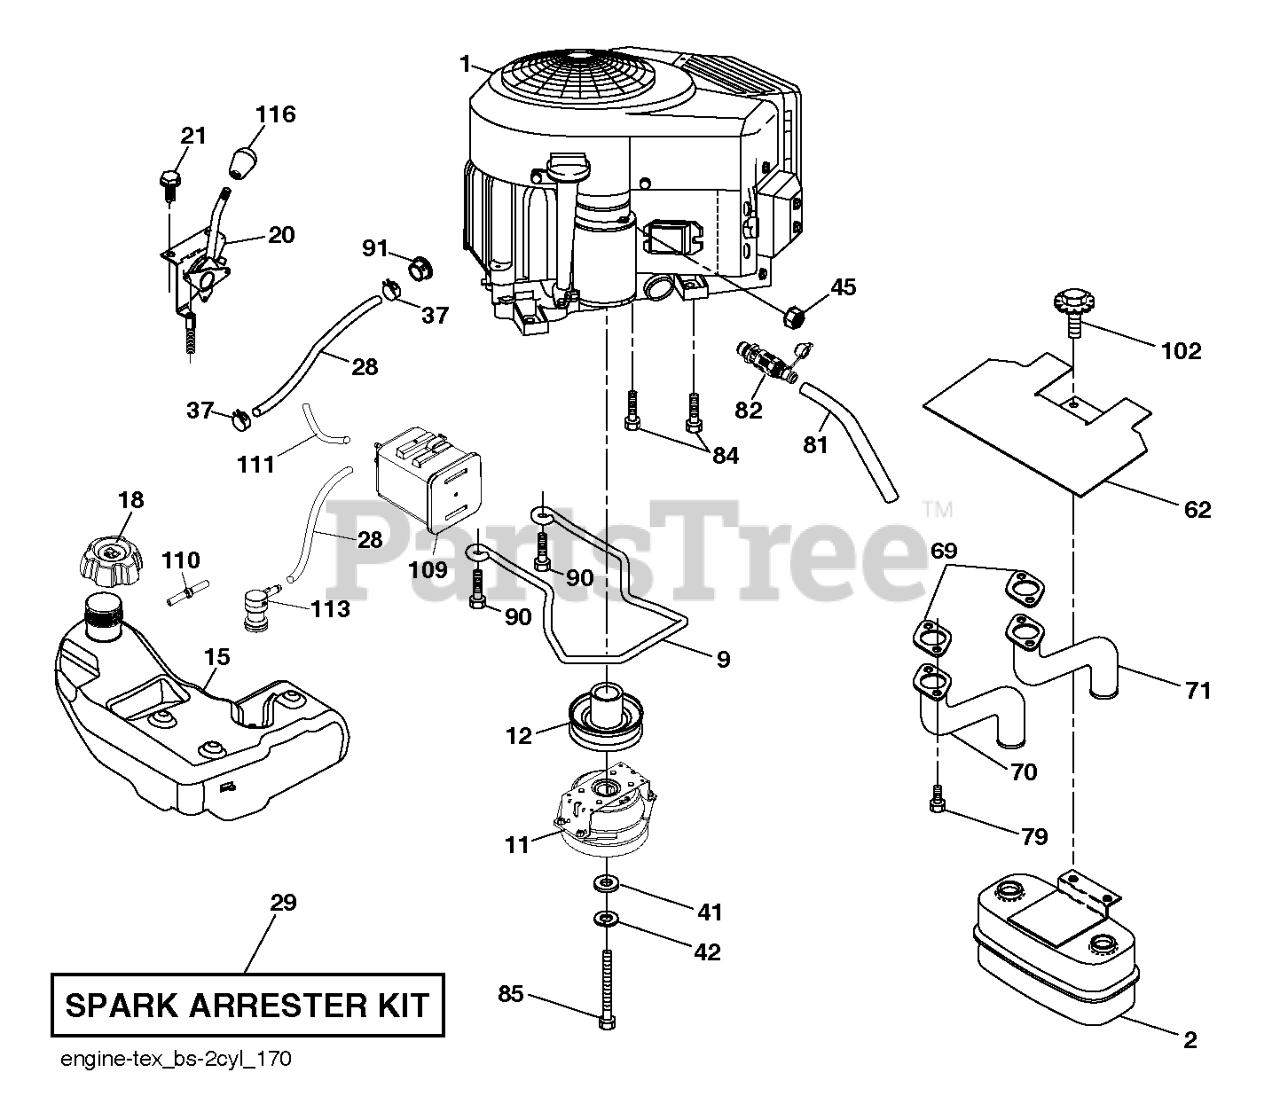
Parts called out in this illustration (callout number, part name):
2	MUFFLER.ASM.TWIN.MNTG.BRACKET
9	KEEPER.BELT.ENG.4.25"2.BLT.431
9	Keepers
11	CLUTCH.OGURA.5.0PD.GT1.5A-EH07
12	PULLEY.ENGINE.TUFFTORQ
15	FUEL TANKS
15	FUEL.TANK.ASM.3.0GAL.REAR.2019
15	Tanks
18	CAP ASSY FUEL 3" GRAY
18	Fuel Caps
18	FUEL CAP
20	THROTTLE.PRO.RSTART. 38
28	LINE.FUEL.64"REAR.EMIS
29	KIT.SPARK ARRESTOR 794945 B&S
37	HOSE CLAMP
62	SHIELD.HEAT.MUFFLER
69	GASKET.MUFFLER
70	EXHAUST.TUBE.RH.B&S.TWIN.INTEK
71	EXHAUST.TUBE.LH.BS/TWIN
81	TUBE, DRAIN OIL ASM.
82	VALUE.OIL.DRAIN
84	SCREW.3/8-16
85	BOLT.HEX.7/16-20X3.75.GR5.RED
90	SCREW 3/8-16X1
91	BUSHING.1.375OD
102	SCREW
109	CANNISTER, CARBON
110	VALVE.ASM.ANTI-SLOSH
111	TUBE.PURGE.FUEL.1875
113	VALVE.SLANT.CARTRDG.90 DEG.TEX
116	KNOB - SHIFT
